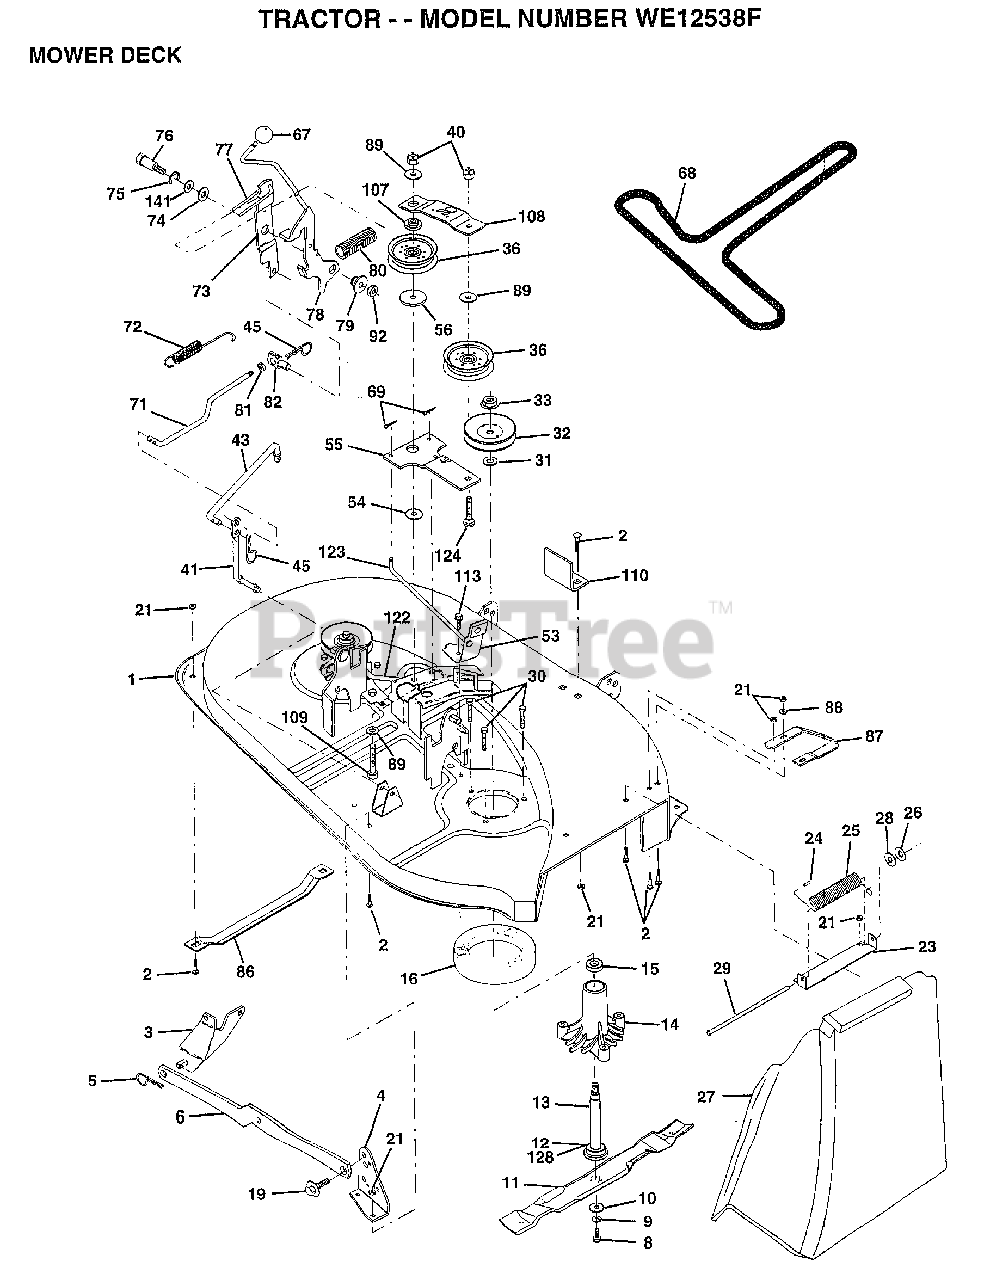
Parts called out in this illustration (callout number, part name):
2	BOLT
3	BRKT ASM SWAY BAR
4	BRKT DECK SW BAR
8	BLADE BOLT
10	WASHER.HARD.BLADE
11	"BLADE.38"" HIPERF"
12	BEARING.BALL
14	HSG ASM MANDREL
15	BEARING
16	STRIPPER RND MWR
19	BOLT SHD 5/16-18
23	BRKT DEFLECTOR
24	CAP-SLEEVE LT
25	SPRING TORSION
26	NUT PUSH M
27	DEFLECTOR-SHLD T
28	WASHER
29	ROD-HINGE T
30	"SCREW-THD ROLL,WA"
31	WASHER
32	PULLEY.MANDREL.38
36	FLAT IDLER PULLEY
41	PIVOT ROD
43	CLUTCH ROD SECOND
45	RETAINER M
53	BRAKE ASM
54	HARDENED WASHER
55	IDLER ARM ASSY
56	SPACER RETAINER
67	KNOB.RD.7/16-14
68	BELT.V.T-PATH
71	ROD CLUTCH 38/42
72	RETURN SPRING
73	CLUTCH ARM SECOND
74	WASHER
75	RING
76	SHOULDER BOLT
77	SPRING KEEPER
78	LEVER.ASM.CLUTCH
79	BUSHING
80	SPRING.CLUTCH.MWR
81	NUT
82	TRUNION ADJ
86	RUNNER-LH M
87	RUNNER RH
88	WASHER M
89	WASHER GT
92	NUT
107	RETAINER SPACER
108	IDLER ARM STIFF
109	BOLT
110	UPSTOP DECK FT 38
113	SCREW
122	BRAKE ROD LH
123	BRAKE ROD RH
124	BOLT
128	WASHER.FELT.
141	WASHER .T
